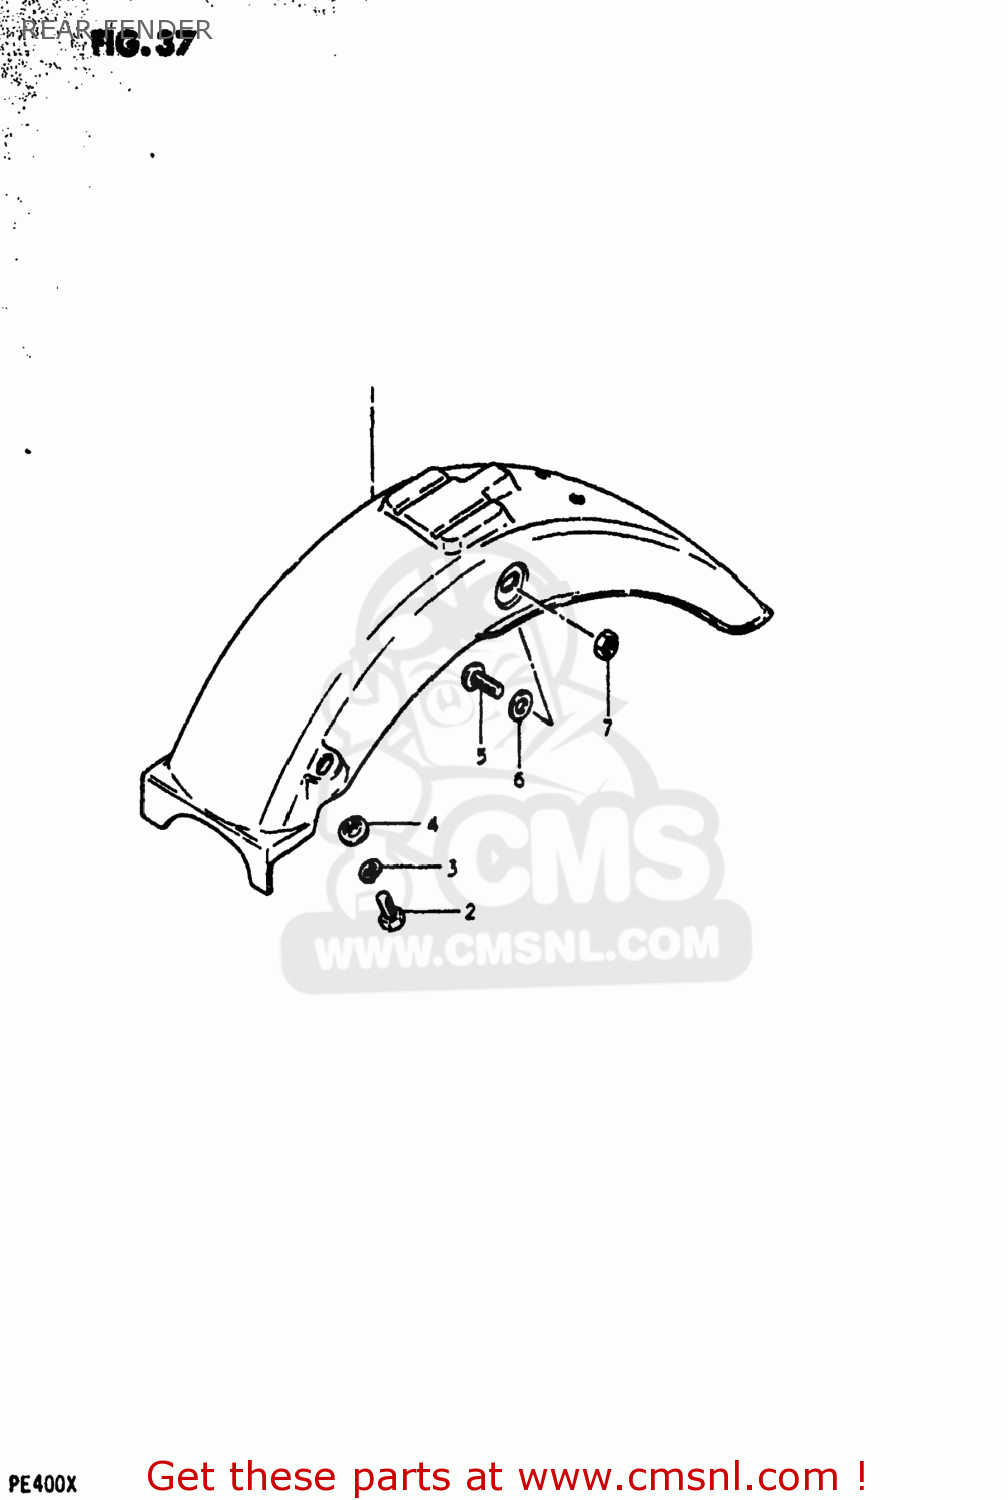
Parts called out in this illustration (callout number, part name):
1	FENDER,REAR
2	BOLT
3	LOCK WASHER
4	WASHER
5	SCREW
6	WASHER (6.5X20X1.2)
7	NUT
